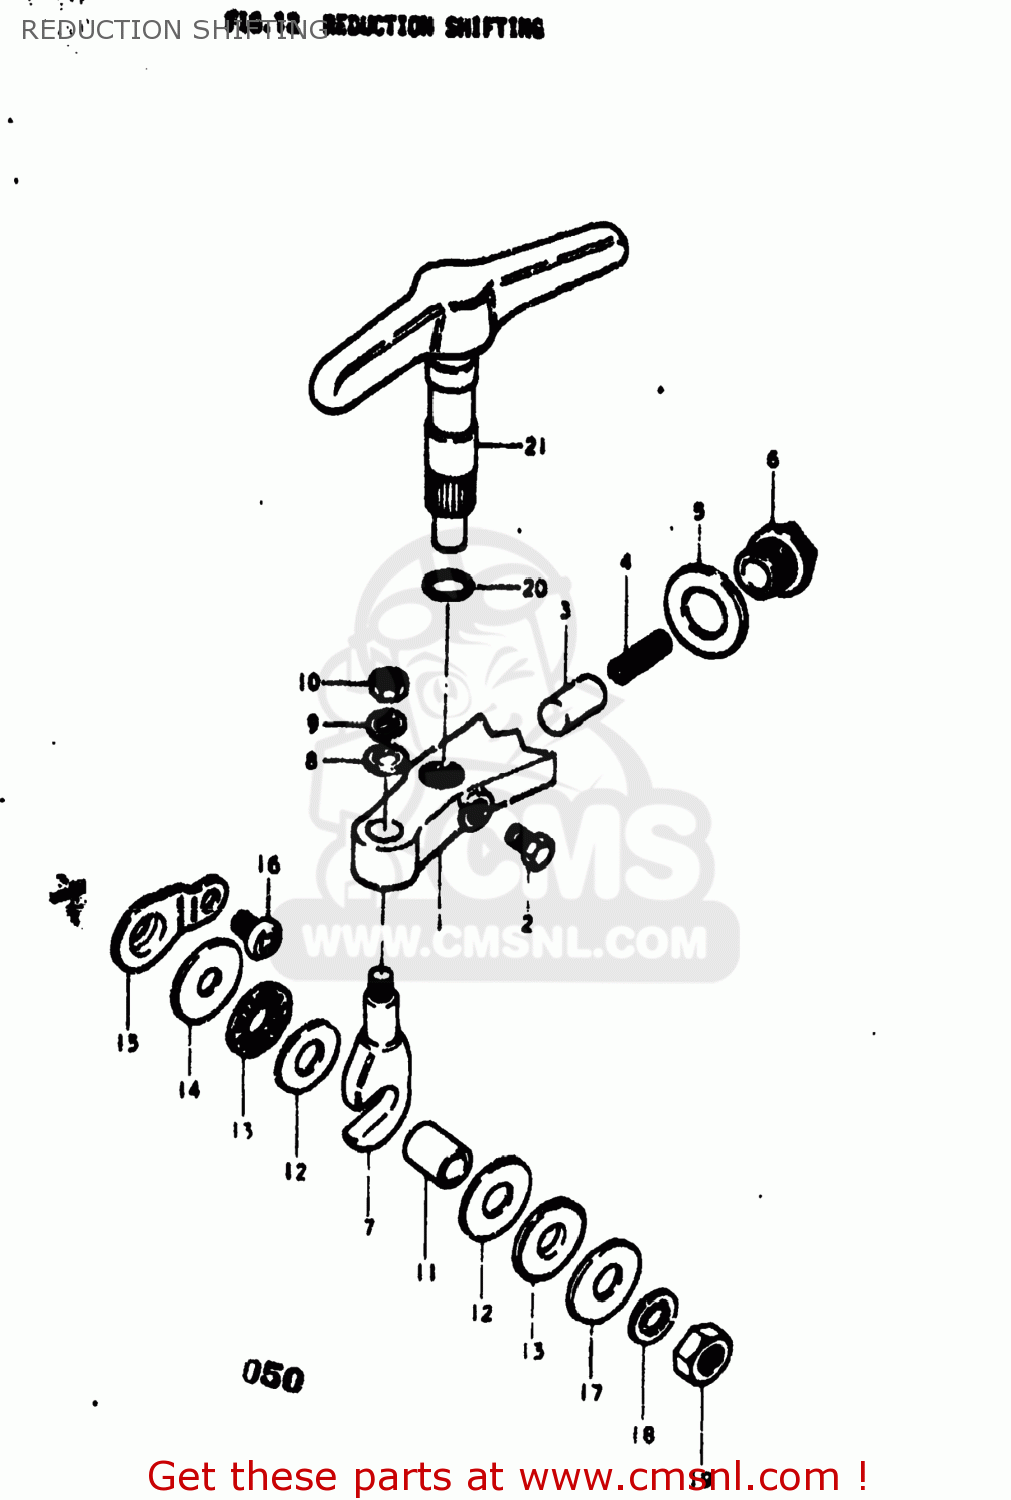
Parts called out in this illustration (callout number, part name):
1	ARM,REDUCTION SHAFT
2	BOLT
3	STOPPER,GEAR SHIFTING
4	SPRING
5	NUT
6	HOLDER,SHIFTING CAM STOPPER
7	REDUCTION SHIFTING ARM PIN
8	WASHER
9	LOCK WASHER
10	NUT
11	SPACER(6X10X12.2)
12	WASHER(10.1X21.4X0.8)
13	BEARING(10X22X2.8)
14	WASHER
15	REDUCTION ROD DUST SEAL
16	SCREW
17	WASHER (6X22X2)
18	LOCK WASHER
19	NUT
20	O RING(D:1.3,ID:9.6)
21	REDUCTION SHIFTING LEVER
